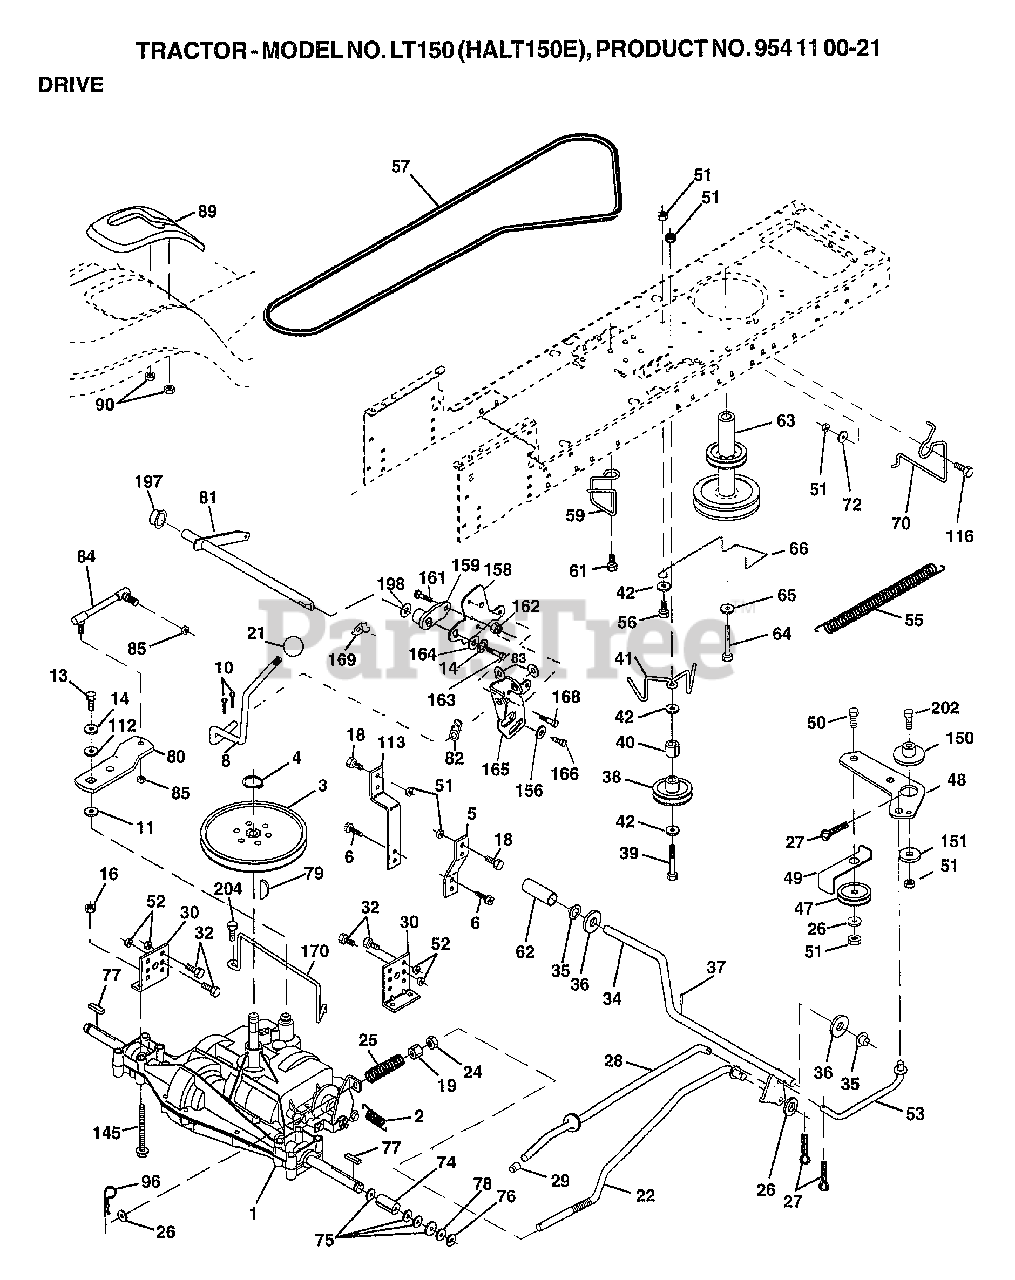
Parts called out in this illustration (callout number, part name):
4	RING, RETAINER
6	SCREW
8	ROD.SHIFT.FENDER.ADJ
10	PIN COTTER 1/8 X 1 CAD
13	BOLT 1/4-28 GR 8 W/PATCH
14	WASHER, LOCK 1/4
16	LOCKNUT
18	BOLT FIN HEX 3/8-16 X 1
19	LOCKNUT
24	NUT HEX JAM 3/8-16 UNC
26	WASHER 13/32 X 13/16 X 16 GA
27	PIN COTTER 1/8 X 3/4 CAD
30	BRK MTG TRANSAXLE
32	BOLT, HEX 5/16-18 X 3/4
36	WASHER 21/32 X 1 X 16 GA
39	BOLT RDHD 3/8-16 X 2-3/4 GR 5
42	WASHER
50	BOLT HEX HD 3/8-16 X 1-1/2
51	NUT, CROWNLOCK 3/8-16
52	LOCKNUT, CROWN 5/16-18
56	BOLT, HEX 3/8-16 X 1-1/4
64	BOLT HEX
65	WASHER LOCK HVY HLCL SPR 7/16
72	WASHER 13/32 X 1-1/4 X 12 GA
76	E-RING #5133-75
81	SHAFT ASM CROSS TAPERED
83	WASHER 17/32 X 3/4 X 16 GA
84	TRANSAXLE LINK
112	WASHER 9/32 X 3/4 X 10 GA
116	BOLT RDHD SQ NECK 3/8-16 X 1.25
150	BUSHING BELLCRANK
151	WASHER
156	WASHER.SORTED
158	BRKT.SHIFT.MOUNT
159	HUB.TAPERRED FLANGE SHIFT
161	BOLT, CARRIAGE 1/4-20 X 3/4
162	NUT CROWNLOCK 1/4-20
165	BRKT.PIVOT.LEVER
166	SCREW 5/16-18X5/8
168	BOLT SHOULDER 5/16-18X.561
169	PLATE.FASTENING.CROSS.SHAFT
170	KEEPER BELT
197	NYLINER SNAP-IN
202	BOLT, CARRIAGE 3/8-16 X 1-1/2 GR.5
